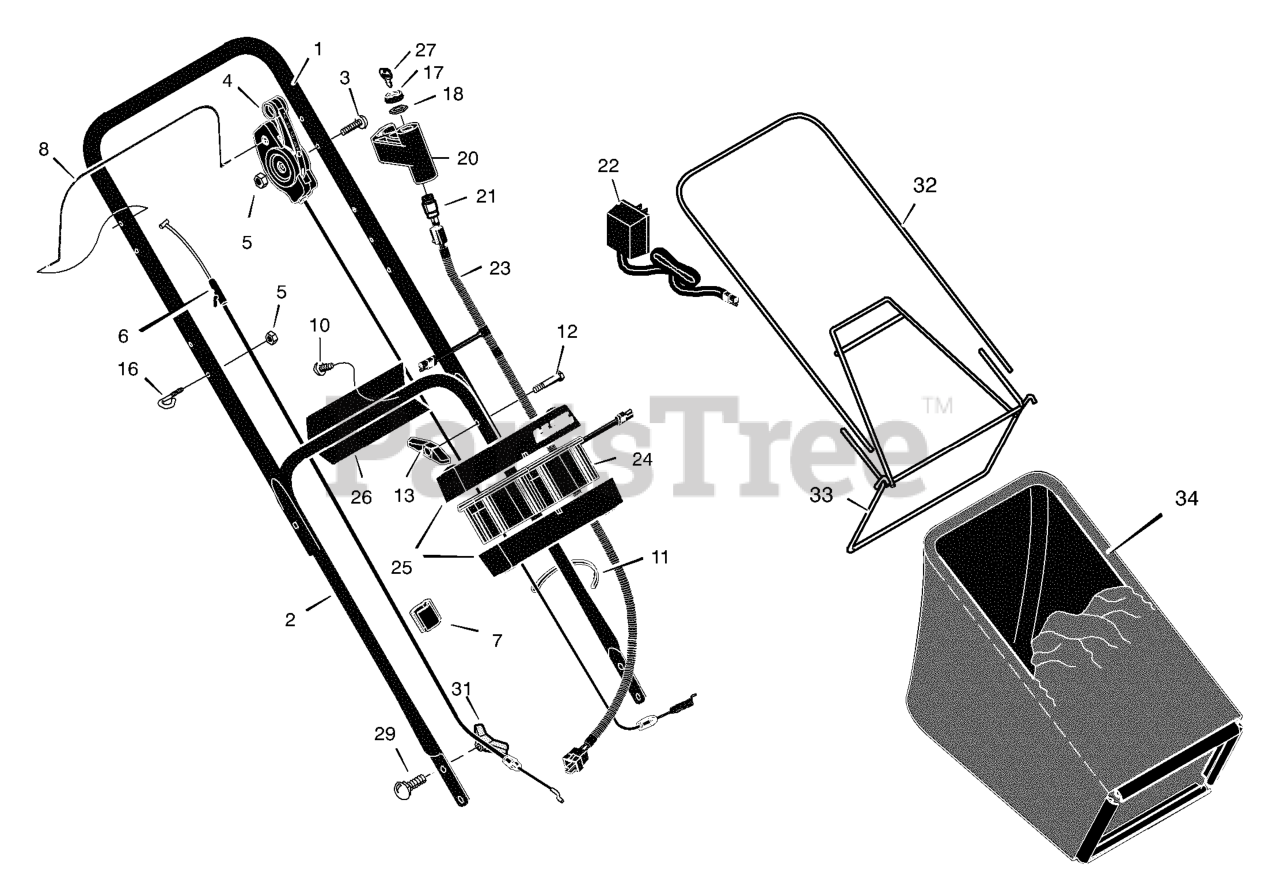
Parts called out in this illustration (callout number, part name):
1	Handle, Upper (Black)
2	Handle, Lower (Black)
4	Control, Drive
5	Locknut
6	Cable, Stop (Briggs)
7	Fastener, Double Cable
8	Lever, Stop
11	Fastener, Cable
13	Knob
16	Guide, Rope
17	Cap
18	Nut
20	Cover, Ignition
21	Switch Ignition & Key
22	Charger, Battery
23	Harness, Wiring
24	Battery
25	Case, Battery
26	Bracket, Battery
27	Key, Ignition
29	Bolt, Carriage
31	Knob, Plastic
32	Tube, Bag
33	Frame Assembly
34	Bag, Cloth
